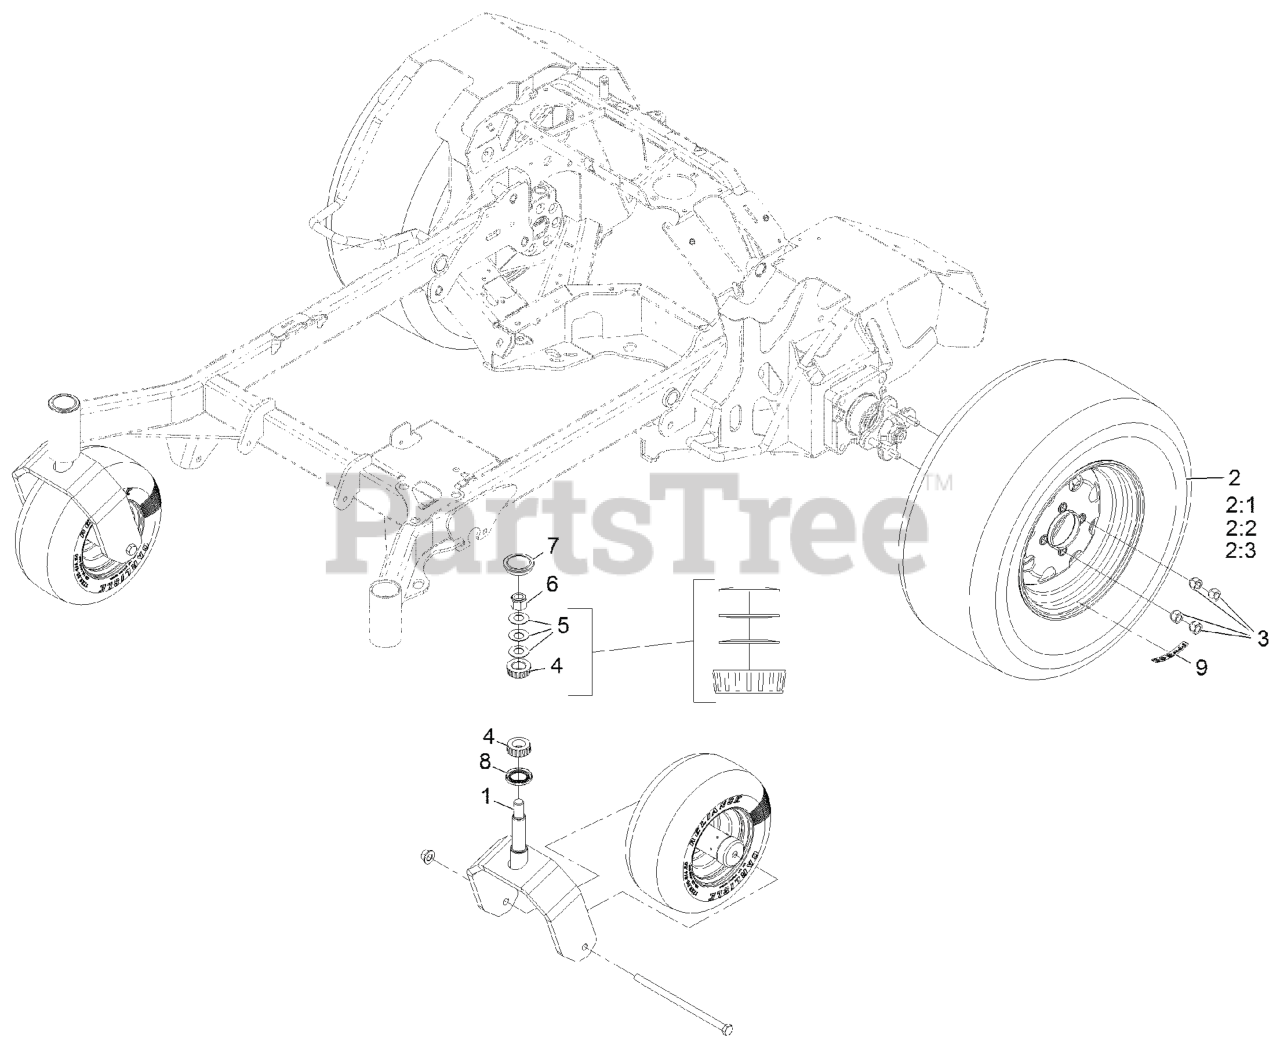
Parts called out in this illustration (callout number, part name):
2	ASM, WHEEL AND TIRE
2:1	TIRE, 23 X 9.50-12
2:2	RIM, 12 X 7
2:3	Stem-Valve
3	NUT-LUG
4	Cone-Bearing Tapered Roller
5	WASHER-BELLVILLE
6	NUT-LOCK, NI
7	CAP-GREASE
8	SEAL-GREASE
9	DECAL-TORQUE, WHEEL HUB LUG
